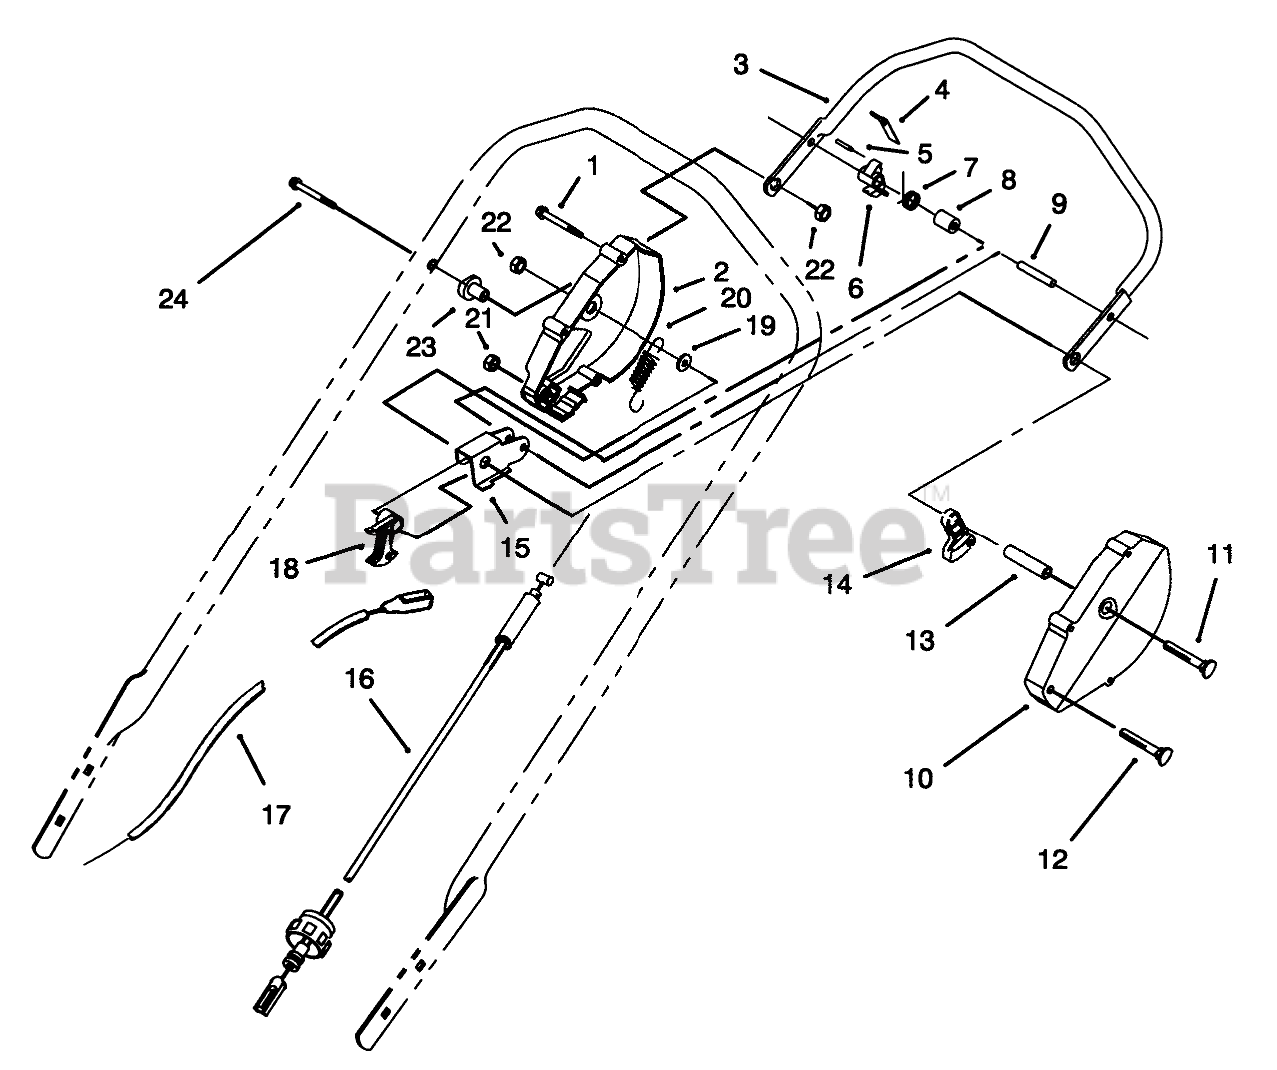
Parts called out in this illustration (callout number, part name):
1	SCREW-HWHTF
2	Housing-Control R.H. (Incl Ref. #4 & 5)
3	Bar-Control
4	SPRING-LEAF
5	PIN-INSERT
6	HOOK-CONTROL
7	SPRING-TORSION
8	SPACER
9	PIN-ROLL, SLOTTED
10	HOUSING-CONTROL, LH
11	OBS MATERIAL EXCEPT FOR SERVICE
12	SCREW-HANDLE
13	TUBING-SPACER
14	LEVER-TRACTION
15	ROCKER
16	TRACTION CABLE
17	CLUTCH CABLE
18	LEVER-CABLE
19	WASHER-NYLON
20	SPRING-DETENT
21	NUT-LOCK NI
22	NUT-LOCK NI
23	SPACER-SUPPORT
24	SCREW-HANDLE
